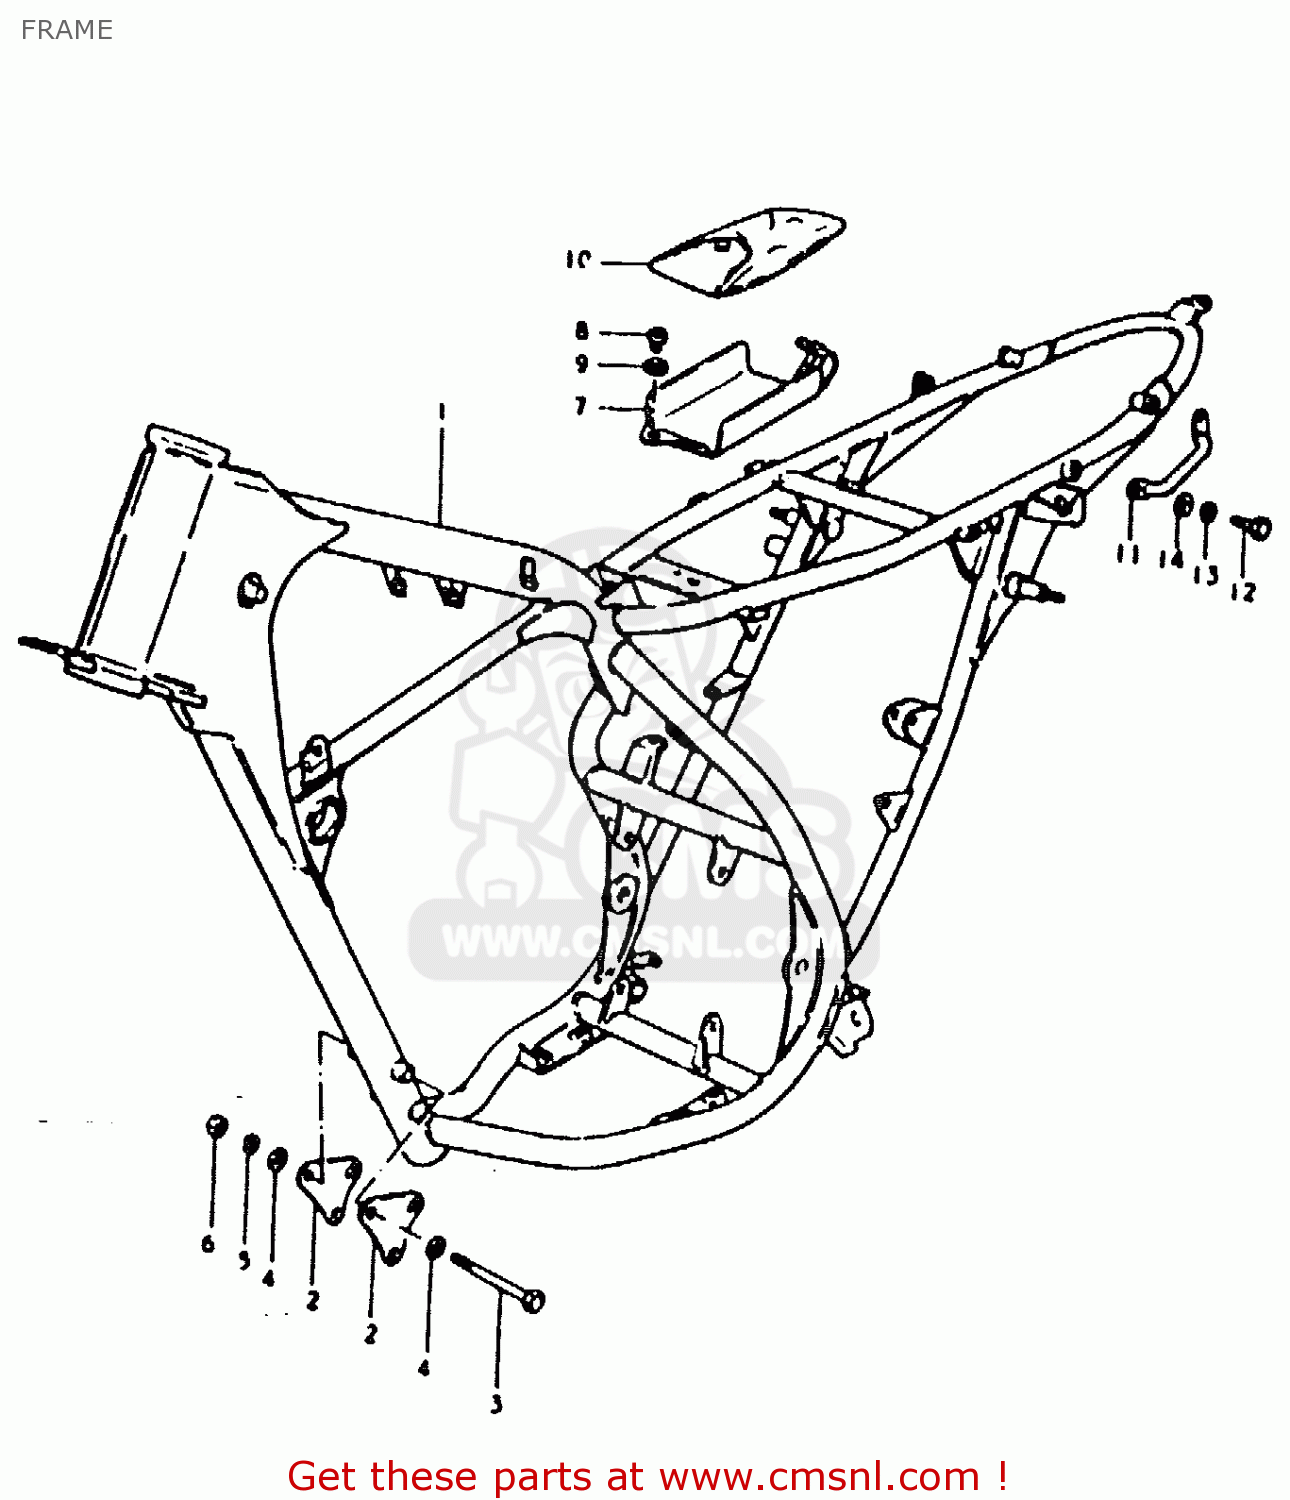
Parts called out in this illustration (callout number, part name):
1	FRAME
2	PLATE,ENG MTG
3	BOLT,8X75
4	WASHER
5	LOCK WASHER
6	NUT
7	HOLDER,TOOL
8	SCREW
9	WASHER
10	TOOL SET
11	GRIP,FRAME HANDLE
12	BOLT
13	LOCK WASHER
14	WASHER
